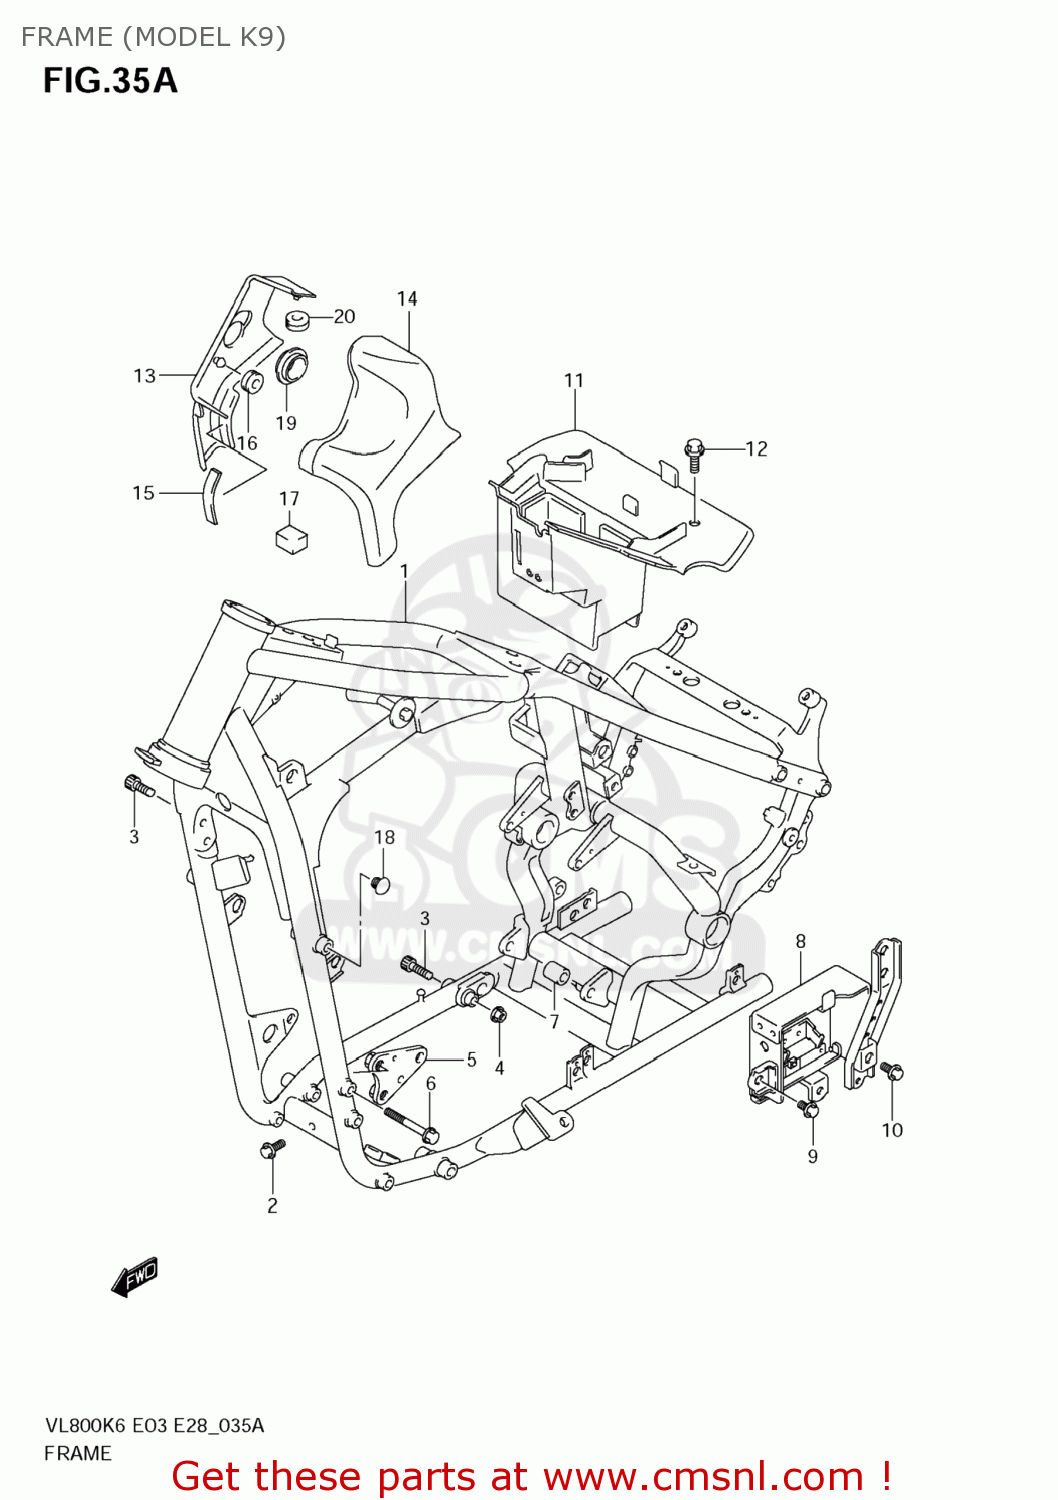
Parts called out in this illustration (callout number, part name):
1	FRAME(BLACK)
2	BOLT
3	BOLT
4	NUT
5	PLATE,ENGINE MOUNT NO.1,L
6	BOLT(8X65)
7	SPACER,ENG MTG LR
8	HOLDER,ELECTRIC PARTS
9	BOLT
10	BOLT, HOLDER
11	HOLDER,ELECTRI
12	BOLT(6X16)
13	COVER,FRAME HEAD,R(BLACK)
14	COVER COMP,FRA
15	CUSHION,FR FENDER
16	CUSHION
17	CUSHION,FR FENDER SIDE
18	CAP(OD:14)
19	CAP
20	CUSHION
